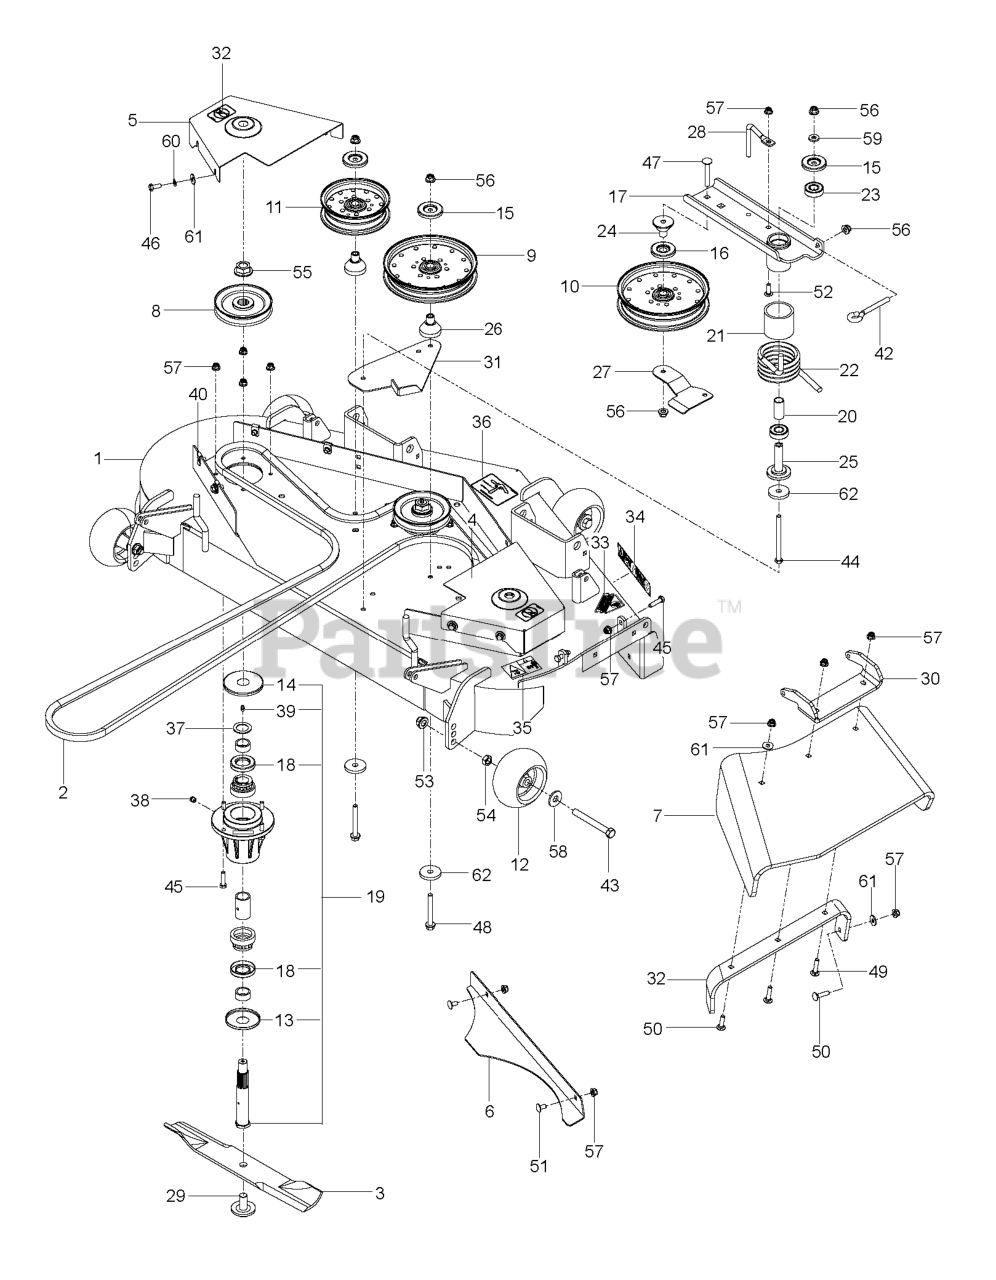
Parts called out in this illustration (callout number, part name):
1	JOYSTICK KIT
2	STUD SNAPLOC
3	WASHER JOYSTICK
4	BELLOWS LIFT-COLLISION
5	JOYSTICK KIT
7	PRINTED CIRCUIT ASSY PCBA LIFT
8	SCREW 14MM
9	SCREW ITXPANT
10	JOYSTICK ASSY REAR
11	SCREW ITXPANT
12	CHASSIS KIT
13	SEALING STRIP CHASSIS LOWER 10
14	SEALING STRIP CHASSIS UPPER 10
15	KNOB HEIGHT ADJUSTMENT
16	PRINTED CIRCUIT ASSY COLLISION
17	LOOM LIFT, COLLISION
18	SCREW ITXPANT
19	HOLDER TWIST LOCK
20	WIRING ASSY HMI
21	SCREW ITXPANT
